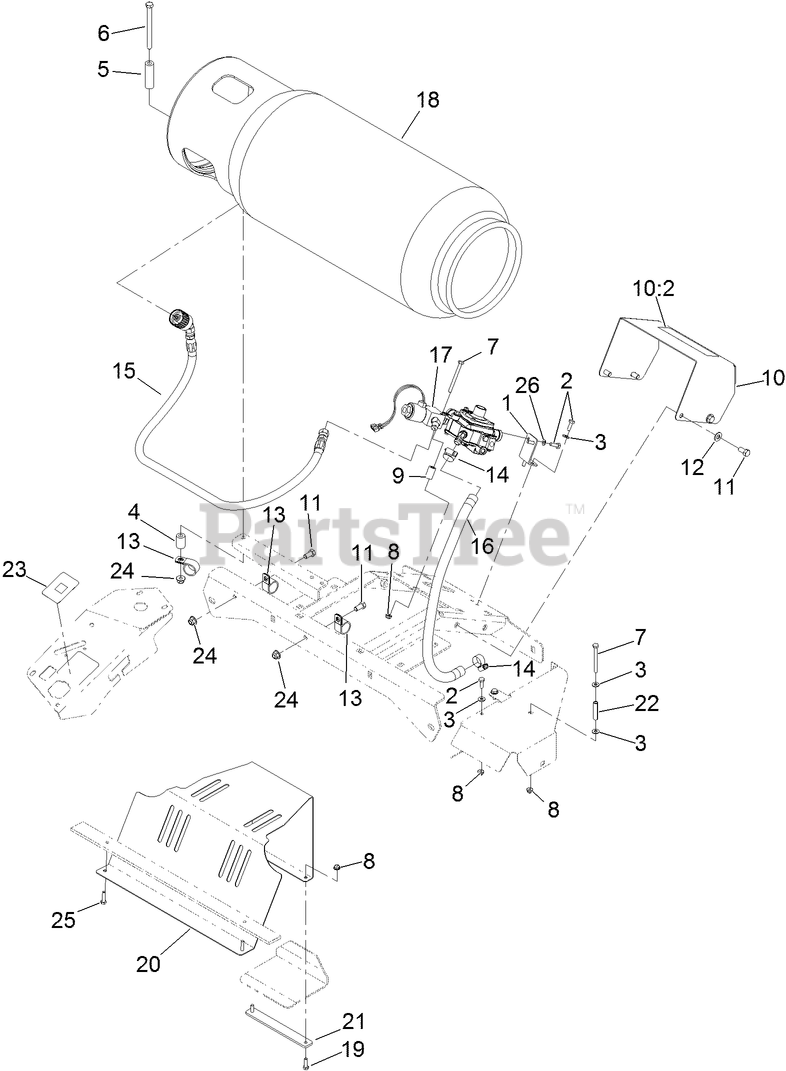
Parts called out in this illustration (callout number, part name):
1	BRACKET-REGULATOR
2	SCREW-HH
3	WASHER-FLAT
4	SPACER-HYDRO CONTROL, LH
5	SPACER-ANCHOR, CLUTCH
6	SCREW-HH
7	SCREW-HH
8	NUT-HF
9	SPACER
10	COVER ASM
10:2	DECAL-TANK REPLACEMENT
11	SCREW-HH
12	WASHER-FLAT
13	CLIP-LOOM
14	CLAMP-HOSE
15	LPG FUEL HOSE ASM
16	HOSE-LPG
17	LPG REGULATOR SOLENOID ASM
18	TANK-LPG
19	SCREW-HH
20	SHEILD-FAN
22	SPACER-SPLIT
23	DECAL-METER, HOUR
24	NUT-HF, NI
25	SCREW-HH
26	WASHER-SPRING
